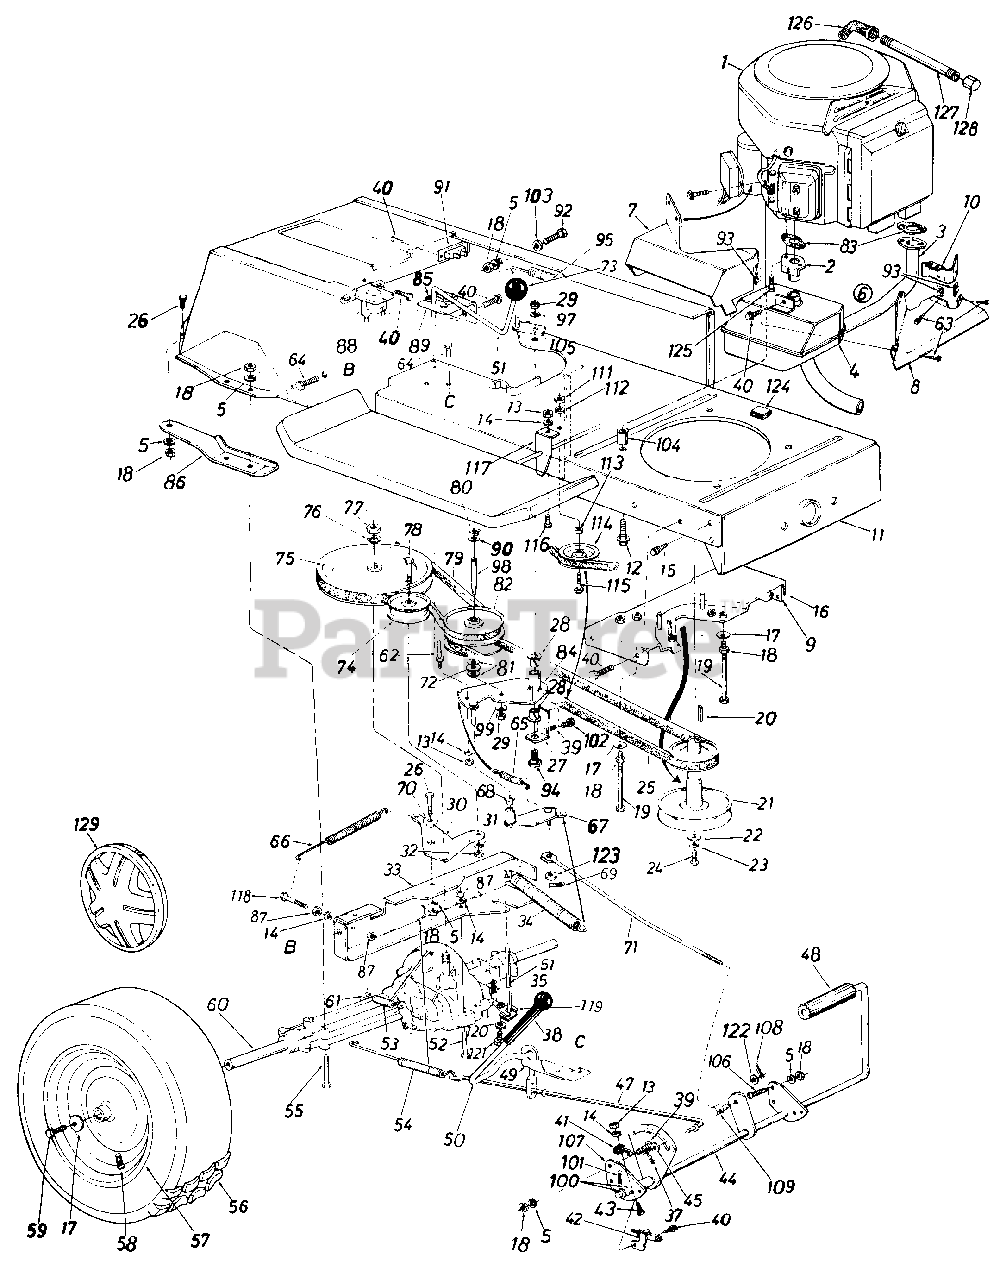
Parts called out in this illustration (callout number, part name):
1	Engine
2	Inlet Tube Ass'y.
3	Formed Tube Ass'y.
4	Exhaust Muffler Sub Ass'y.
5	L-Wash. 5/16" I.D.
6	Muffler Ass'y. Comp.
7	Muffler Heat Shield
8	Front Heat Shield
9	Brake Cable Brk't.
10	Front Heat Shield Ext.
11	Lower Frame Ass'y.
12	Hex Wash. Hd. TT-Tap Scr. 3/8-16 Thd.
13	Hex Nut 1/4-20 Thd.*
14	L-Wash. 1/4" I.D.
15	Hex Wash. Hd. AB-Tap Scr. 5/16" x .75" Lg.
16	Belt Guard Brkt. Ass'y.
17	Bell-Wash. .345" I.D. x .88"
18	Hex Nut 5/16-18 Thd.
19	Hex Bolt 5/16-18 x 4.00
20	Sq. Key 1/4" x 1/4" x 2.00"
21	Engine Pulley
22	Fl-Wash. 7/16" I.D. x 1.25"
23	L-Wash. 7/16" I.D.
24	Hex Bolt 7/16-20 x 1.50" Lg.
25	Variable-Speed Belt
26	Hex Bolt 5/16-18 x .75" Lg.
27	Bearing Shaft Bracket Ass'y.
28	Flanged Nyliner Brg. 5/8" I.D. x .88" Lg.
29	Hex Nut 3/8-24 Thd.
30	Idler Bracket
31	L-Wash. 3/8" I.D.
32	Hex Nut 3/8-24 Thd.
33	Transaxle Support Brkt.
34	Ext. Spring .94" O.D. x 6.7"
35	Inter. Cotter Pin
37	Cotter Pin 3/32" Dia. x .75
38	Grip-Black
39	Truss Mach Scr. 5/16-18 x .75" Lg.
40	Hex Wash. Hd. Self-Tap Scr. 1/4-20 x .50" Lg.
41	Switch Actuator
42	Safety Switch
43	Hex Bolt 1/4-20 x 1.0" Lg.
44	Clutch & Brake Pedal Ass'y.
45	Fl-Wash.
47	Brake Rod 20.9" Lg.
48	Foot Pad
49	Brake Lever Bracket
50	Hill Holder Brake Handle
51	Shift Lever Ass'y.
52	Hex Bolt 1/4-28 x 1.75" Lg.
53	Ext. Spring x 2.5" Lg.
54	Ext. Spring x 7.08" Lg.
55	Hex Bolt 5/16-18 x 2.75"
58	Air Valve
59	Hex Bolt 5/16-24 x .75" Lg.
60	Transaxle Complete-R.H.
61	Brake Return Spring Anchor
62	Belt Guard Pin 1/4-20 Thd.
63	Hex AB-Tap Scr. #10 x .5" Lg.
64	Hex Wash. TT-Tap Scr. 5/16 x .62" Lg.
65	Ext. Spring
66	Ext. Spring .62" O.D. x 6.12"
67	Variable Speed Torque Brkt. Ass'y.
68	Flanged Bearing
69	Cotter Pin 3/32" Dia.
70	Shoulder Spacer .500" Dia. x.27" Lg.
71	Speed Control Link
72	Truss Bearing .56" Dia. x 1 .25"
73	Ball Knob
74	Fl-Idler Pulley 3.25" x .75"
75	1/2" "V"-Pulley 8.0" O.D. x .501 " I.D.
76	L-Wash. 1/2" I.D.
77	Hex Jam Nut 1/2-20 Thd.
78	Hex Bolt 3/8-24 x .75" Lg.
79	Variable-Speed Belt
80	Snap Ring .56" Dia.
81	Fl-Wash.
82	Variable Speed Pulley Ass'y. 5" O.D.
83	Gasket
84	Variable Speed Brkt. Ass'y.
85	Comp. Spring Clip
86	Transaxle Support Brkt.-R. H.
87	Hex Nut 1/4-28 Thd.
88	Solenoid
89	Shift Lever Bracket
90	Teflon Washer
91	Circuit Breaker
92	Hex Bolt 5/16-18 x 1.50" Lg.
93	Speed Nut #10-24 Thd.
94	Shld. Bolt 3/8-24 x 3.12" Lg.
95	Ext. Spring .99" O.D. x 11.0"
98	Shaft .56" Dia. x 3.875" Lg.
99	Bell-Wash. .39" I.D. x 1.12"
100	Fl-Wash.
101	Cotter Pin 3/32" Dia. x .75"
102	Hex Wash. Hd. Scr. 5/16-18 x.62" Lg.
103	Fl-Wash. .34" I.D. x 1.12"
104	Spacer 5/16" I.D.
105	Belt Guard
106	Hex Bolt 5/16-18 x .75' Lg.
107	Pedal Bracket
108	Cotter Pin 3/32 x .75"
109	Ferrule
111	Hex Nut 3/8-16 Thd.
112	L-Wash. 3/8" I.D.*
113	Fl-Wash. .390" I.D. x 1.12"
114	Fl-Idler w/Flanges 2.750
115	Hex Bolt 3/8-16 x 2.00" Lg.
116	Hex Bolt 1/4-20 x .62" Lg.
117	Spring Hanger Bracket
118	Hex Bolt 1/4-28 x 1.25" Lg.
119	Shift Lever Link Ass'y.
120	Bell-Wash. .265" I.D. x .75"
121	Hex Bolt 1/4-28 x .62" Lg.
122	Fl-Wash. .385" I.D. x .62"
123	Fl-Wash. .34" I.D. x .68" O.D.
124	Foam Strip
125	Hex Bolt w/Washer
126	90ø Elbow
127	Pipe Nipple
128	Cap Oil Drain
129	Hub Cap
